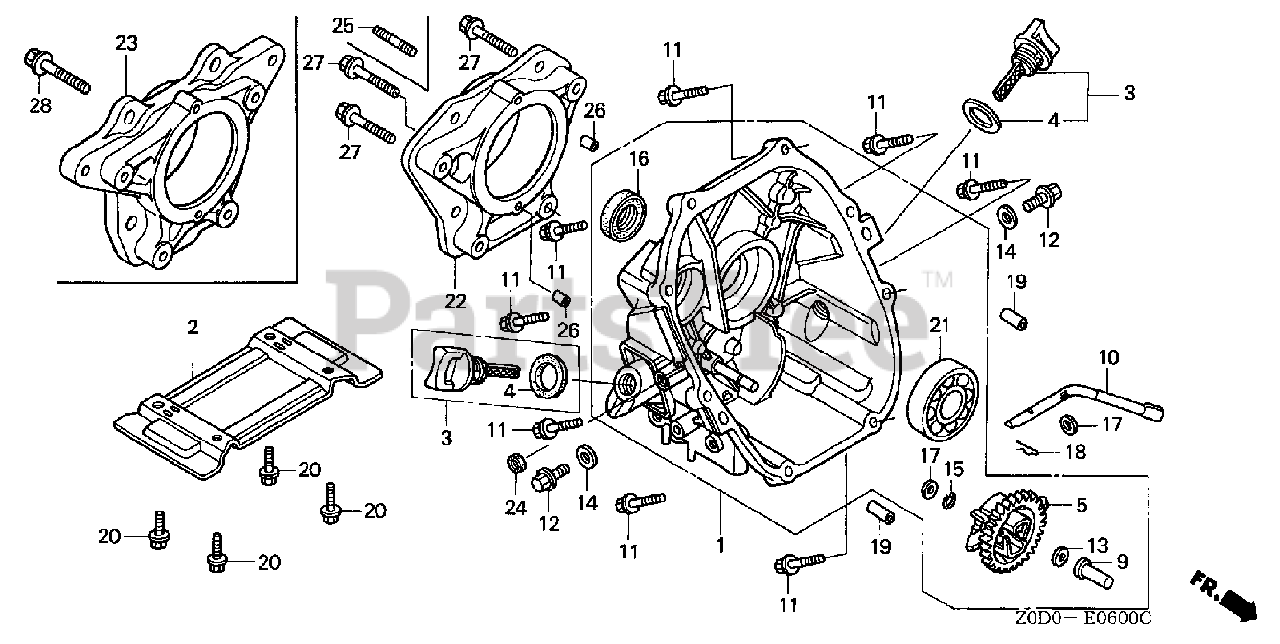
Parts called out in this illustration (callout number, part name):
1	COVER ASSY., CRANKCASE
2	BED, ENGINE
3	CAP ASSY., OIL FILLER
4	GASKET, OIL FILLER CAP
5	GOVERNOR ASSY.
9	SLIDER, GOVERNOR
10	SHAFT, GOVERNOR ARM
11	BOLT, FLANGE (6X25)
12	BOLT, DRAIN PLUG
13	WASHER, THRUST (6MM)
14	WASHER, DRAIN PLUG (10.2MM)
15	CLIP, GOVERNOR HOLDER
16	OIL SEAL (20X32X6)
17	WASHER, PLAIN (6MM)
18	PIN, LOCK (8MM)
19	PIN, DOWEL (8X20)
20	BOLT, FLANGE (8X25)
21	BEARING, RADIAL BALL (6204)
